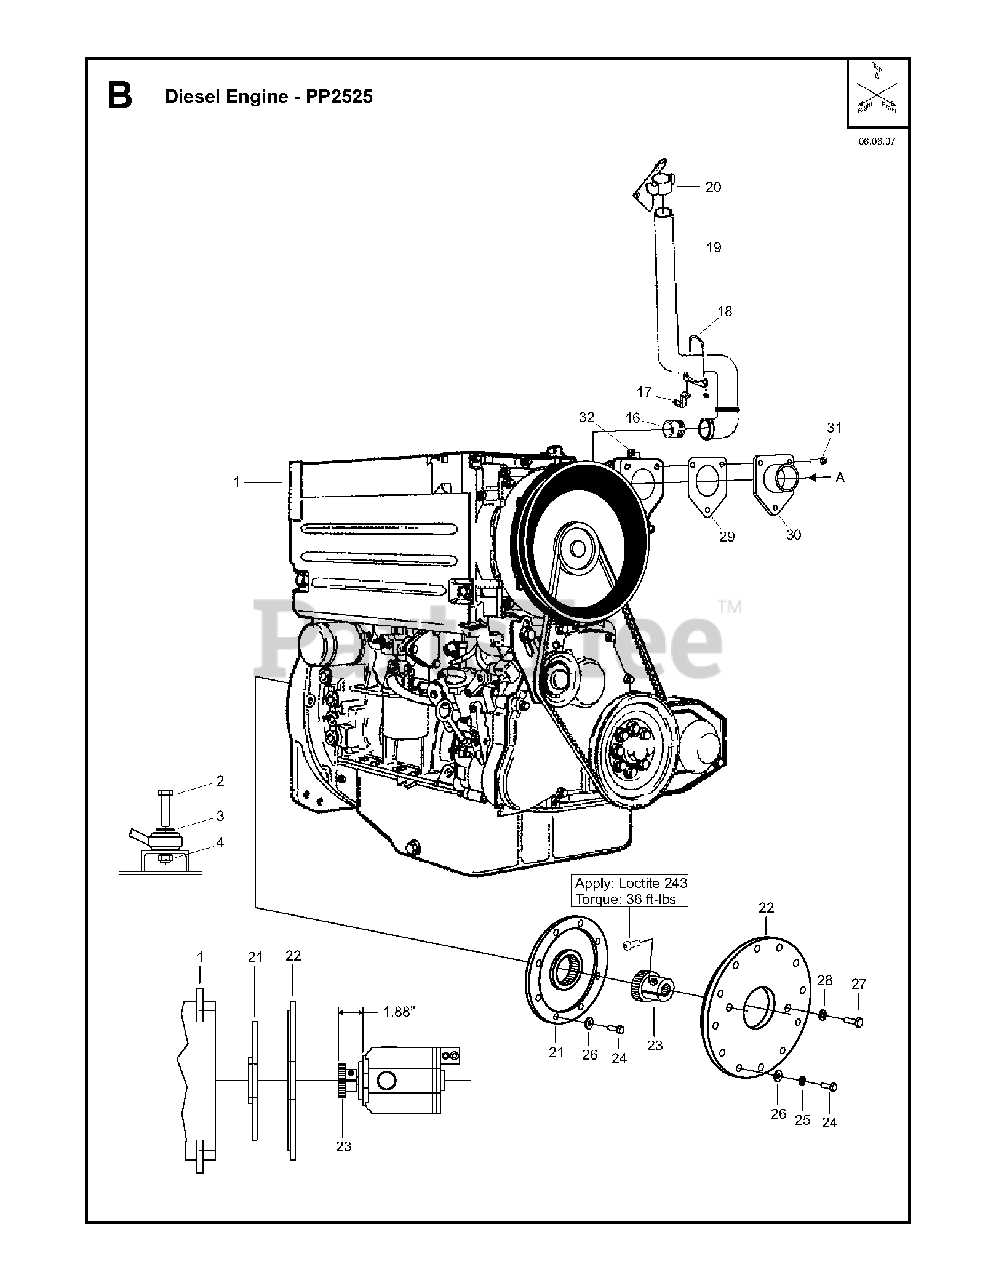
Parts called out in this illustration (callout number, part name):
7	WASHER
8	NUT
23	PUMPIncls SHCS, M10-1.5 x 30
25	WASHER
26	WASHER
